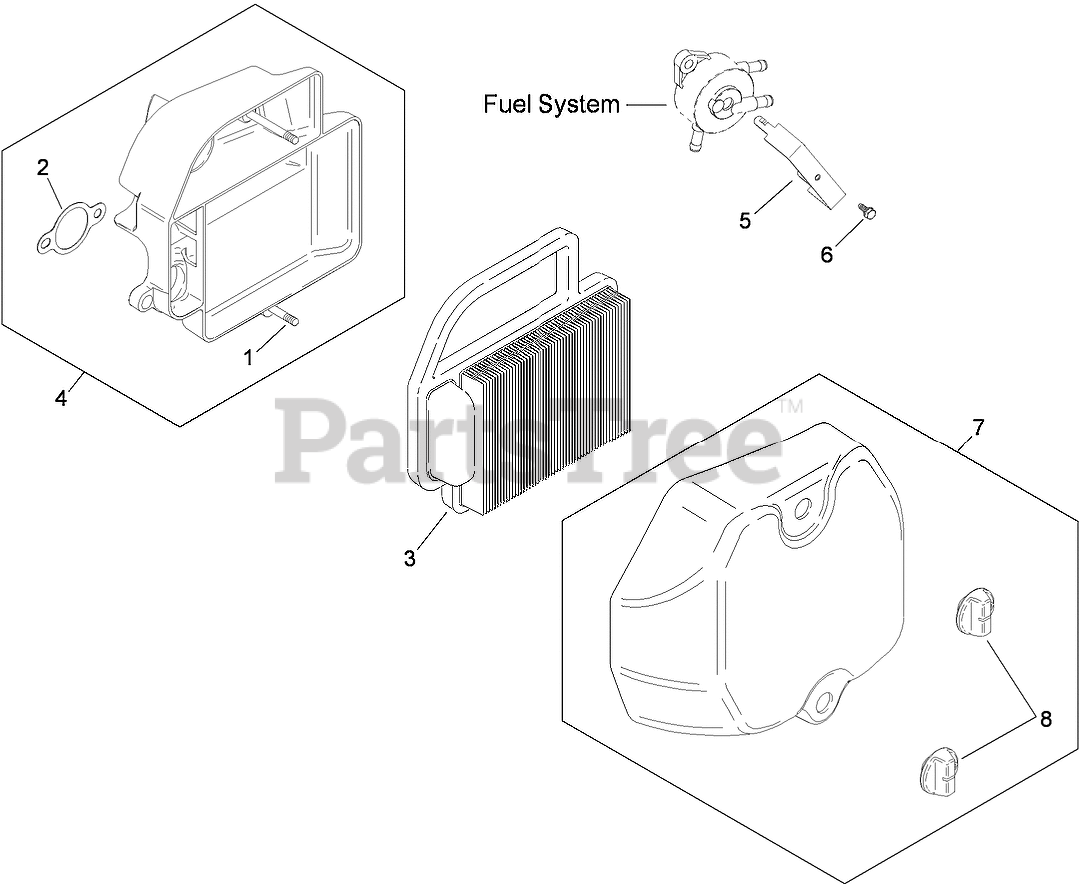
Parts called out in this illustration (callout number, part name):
1	STUD-BASE, AIR CLEANER
2	Gasket-Base, Air Cleaner
3	Element-Cleaner, Air
4	AIR CLEANER BASE ASM (INCLUDES REF 1, 2)
5	BRACKET-PUMP, FUEL
6	SCREW-THRD FRM (M4X0.7X10)
7	AIR CLEANER COVER ASM (INCLUDES REF 8)
8	KNOB-COVER
